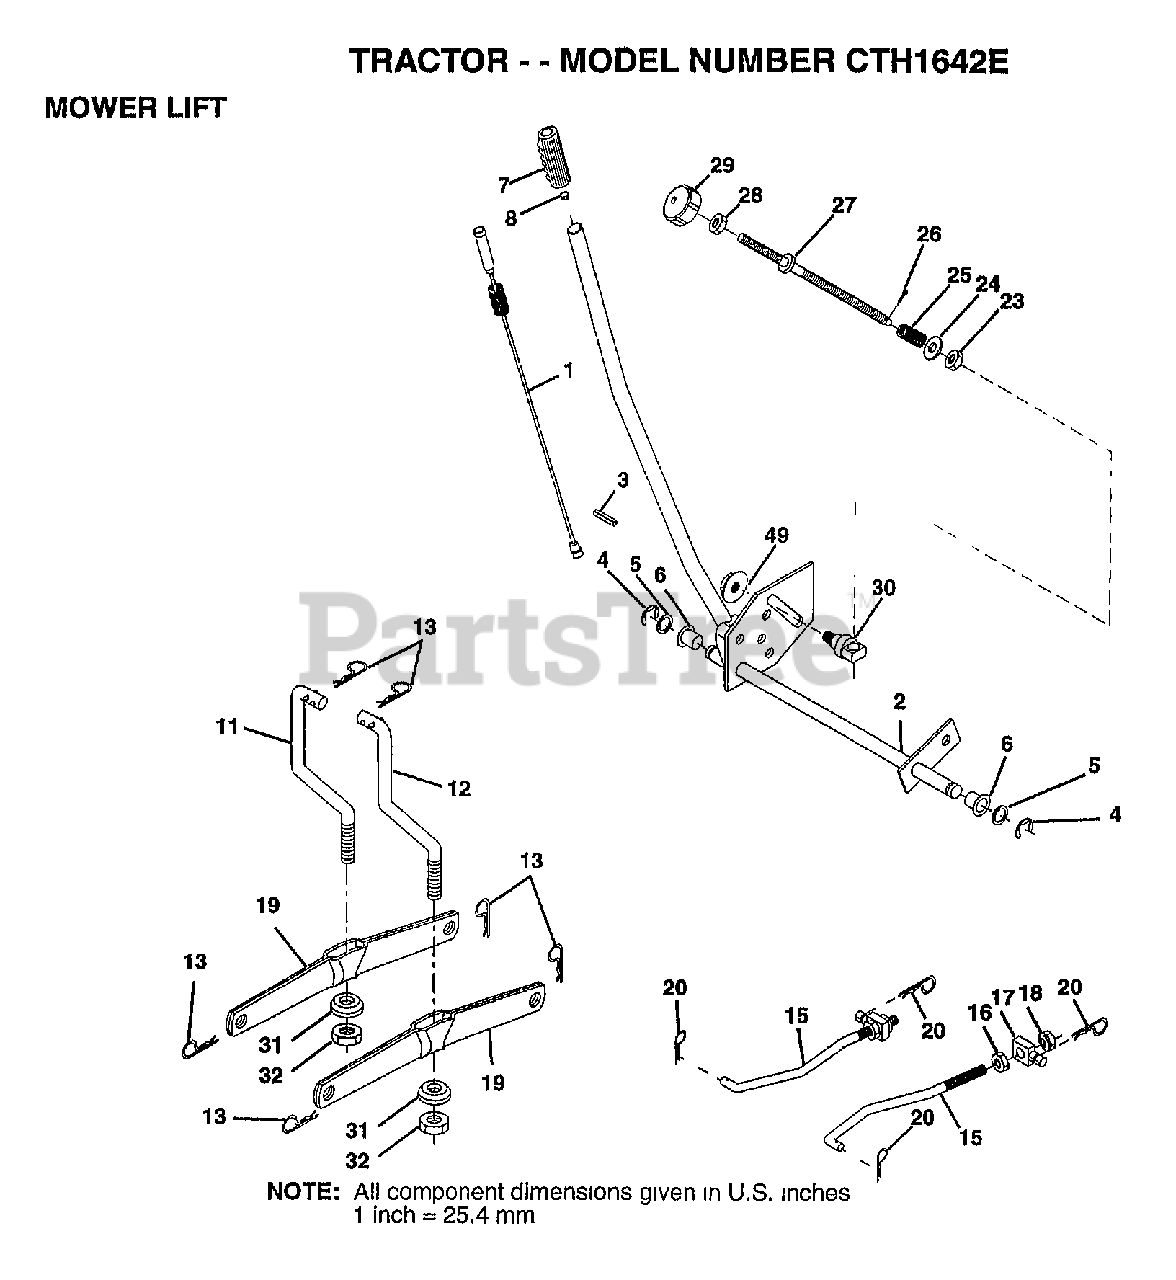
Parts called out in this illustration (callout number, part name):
1	WIRE ASM W.SPRING
2	"SHAFT ASM LIFT,LH"
3	PIN GROOVE
5	WASHER
6	NYLON BEARING
7	GRIP
15	LINK.FRONT
16	NUT
17	TRUNION
18	NUT.LK.W/WSH.1/2.
19	ARM SUSP REAR
20	RETAINER.SPRING
23	NUT T
24	WASHER
25	SPRING.COMP.INF.H
27	ROD.ADJ.LIFT
28	NUT
29	KNOB INF 3/8-16
30	TRUNNION
31	BEARING PVT LH
32	NUT.CROWNLOCK.3/8
49	NUT.HXFLG.LOCK.
